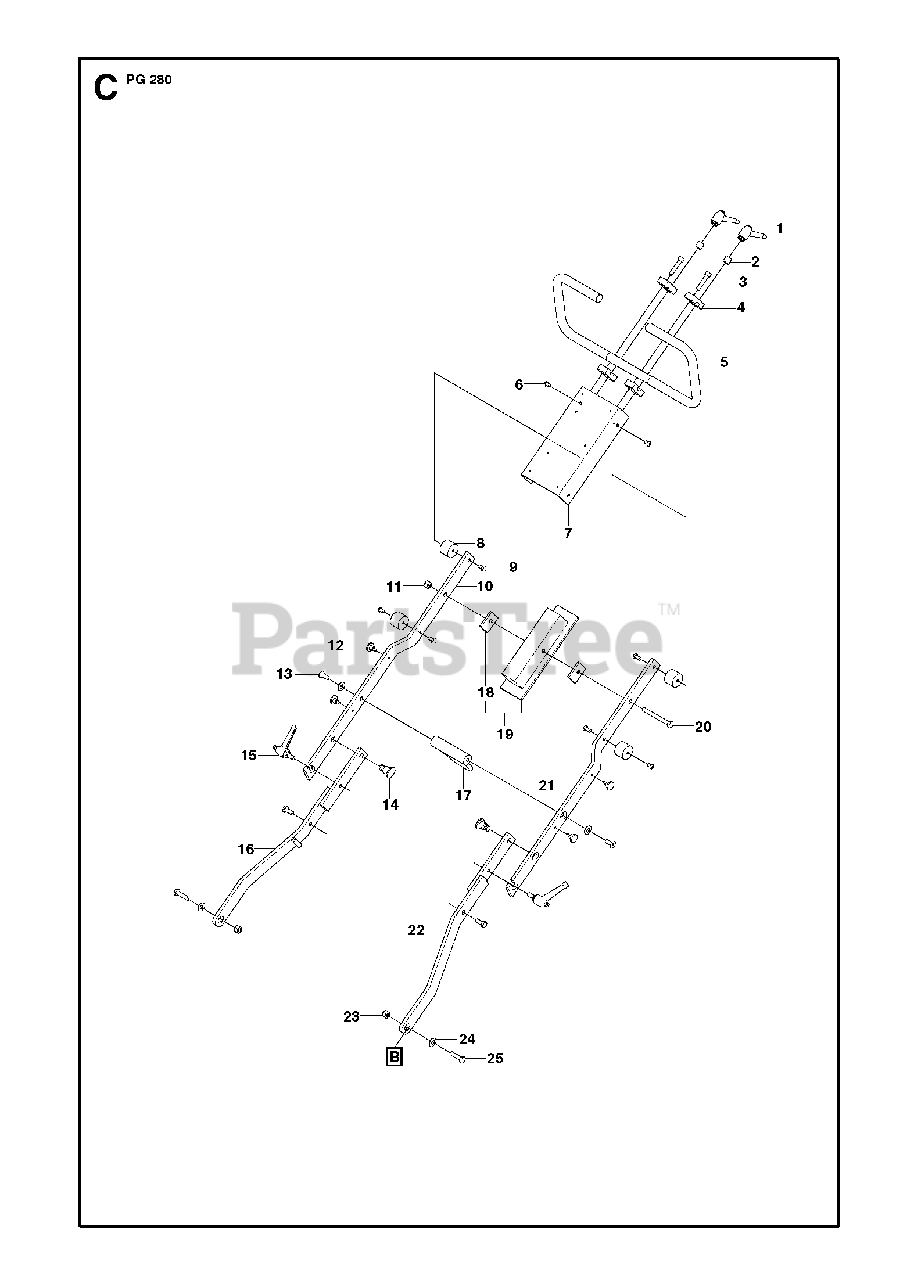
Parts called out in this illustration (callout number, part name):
9	SCREW EHHM
11	HEXAGON LOCKING NUT
23	HEXAGON LOCKING NUT
24	WASHER
